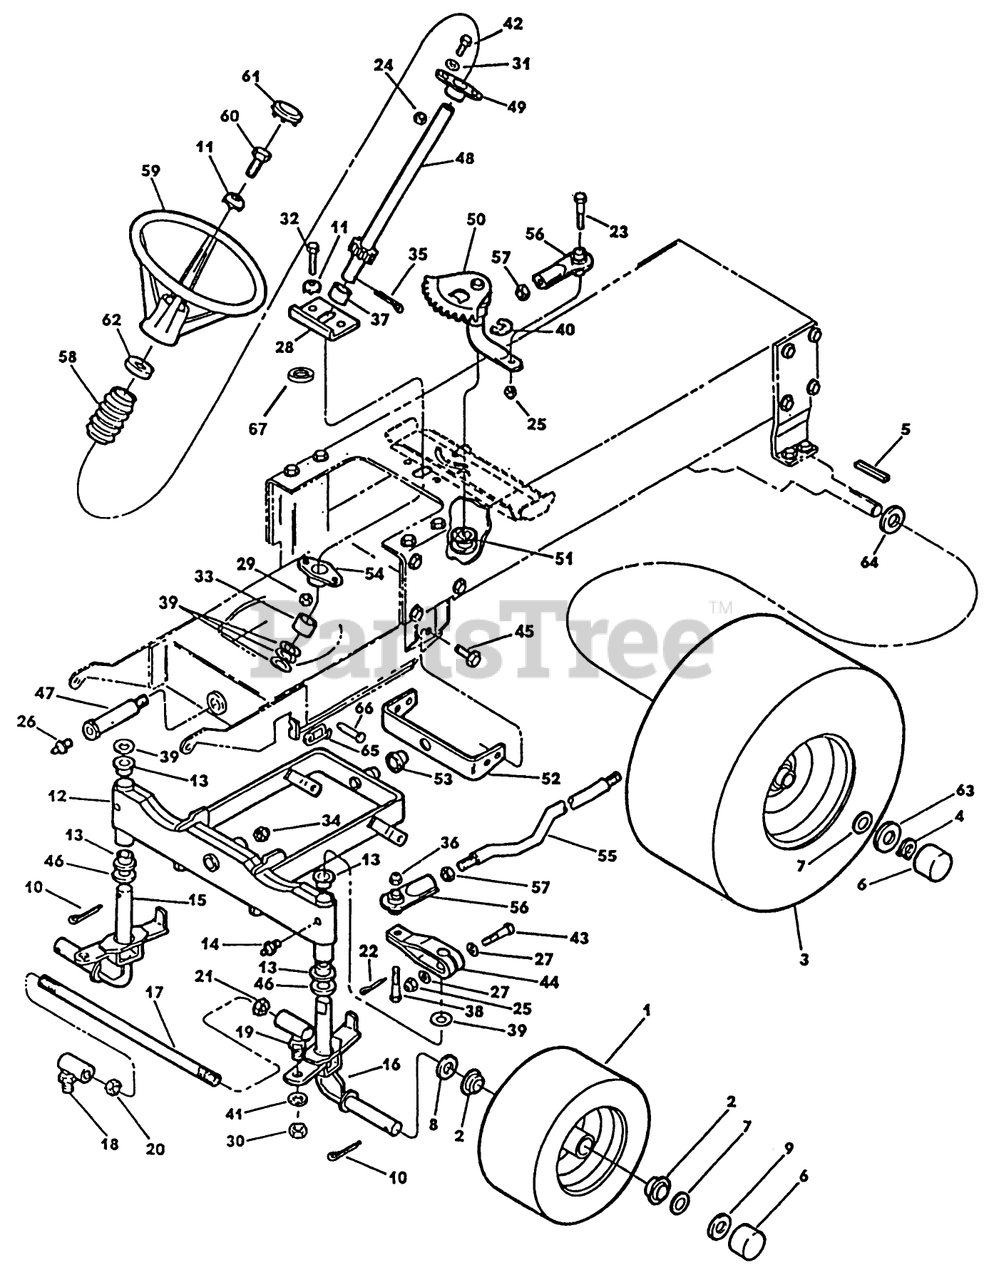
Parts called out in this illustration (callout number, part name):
5	KEY-SQUARE 1/4X1/4
13	BEARING - BRONZE
17	ROD, STEER 1/2
18	BALL JOINT R.H.
19	BALL JOINT L.H.
24	NUT-LOCK, CONE
25	NUT-LOCKING
34	NUT-HEX
42	SCREW-HH
46	WASHER - THRUST
49	BEARING AY.
56	BALL JOINT
57	NUT-HEX
60	SCREW - HEX
